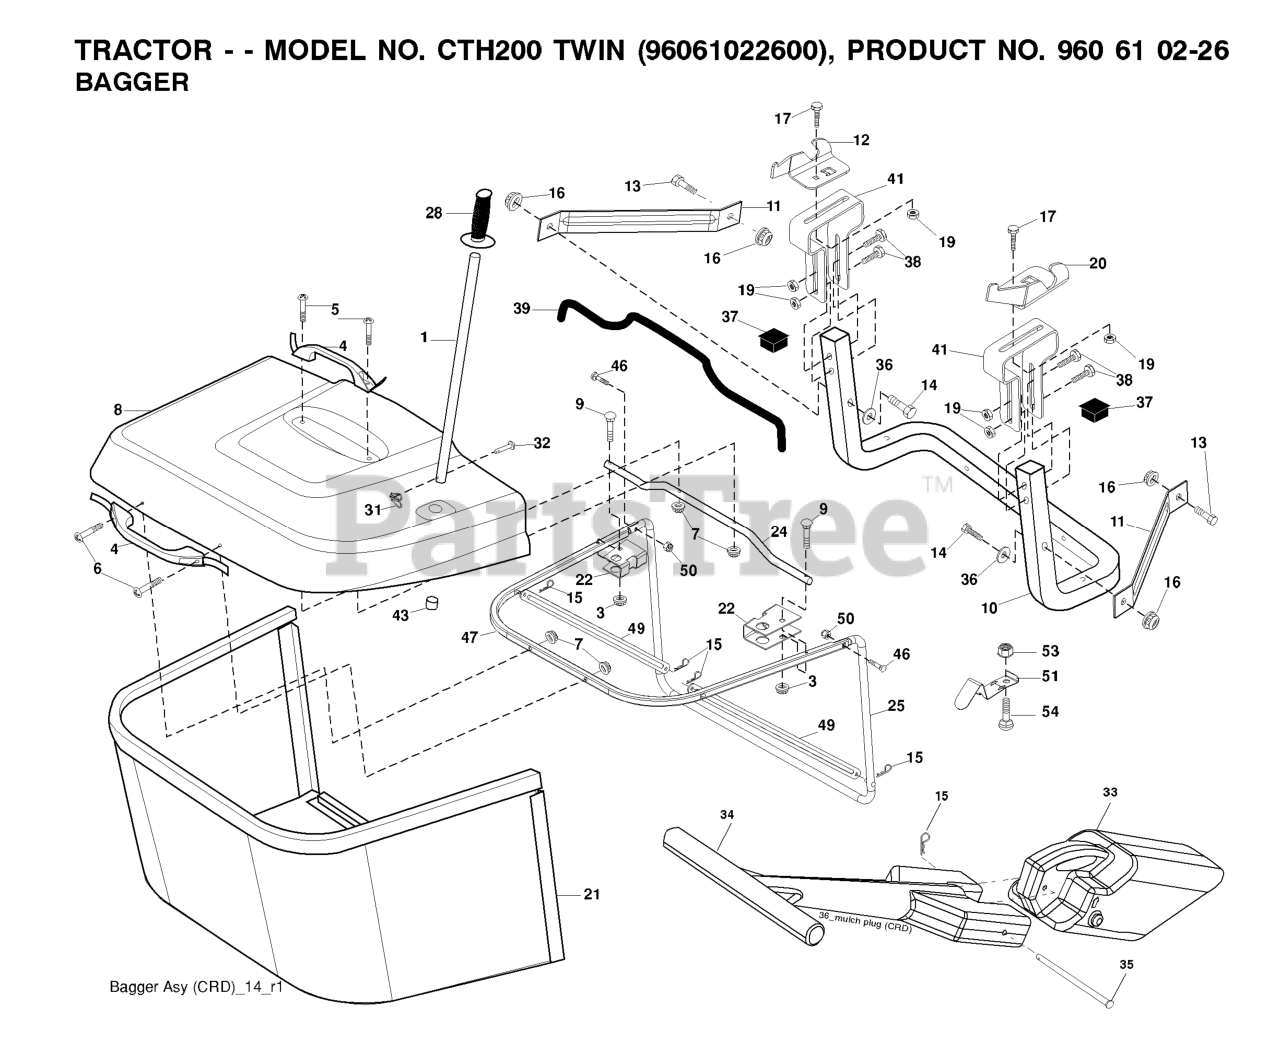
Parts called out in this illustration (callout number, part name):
1	TUBE HANDLE
3	NUT T
4	HANDLE.BAGGER.W/LVRS.BLK.CRD
5	SCREW.PAN.HEAD
6	REPL BY 532 75 00-29
8	COVER.PNT.BGR.CRD.WSLOTS.MS668
9	Bolt Carriage 1/4-20 x 2.25d x Gr.5
10	TUBE
11	BRACKET.SUPPORT.UPPER.BAG.CRD
12	BRKT PIVOT
14	BOLT-HEX EAK
15	RETAINER-SPRNG RB
16	NUT LOCK FLG 3/8-16 UNC
17	RP BOLT 5/16-18 X3/4 ZN/YEL GR
19	NUT LOCK HEX FLANGE 5/16-18
20	BRKT.PIVOT.RH.CRD
21	BAGGER.ASM.CRD.2007
22	BRKT.SIDE.BAG.CRD
24	TUBE.PIVOT.BAG.CRD.BLACK
25	PIPE
28	GRIP.HANDLE.BLACK
31	RETAINER CLIP
32	RIVET,DRILLED
33	MULCH PLUG, CTH150
34	HANDLE.MULCHER.92.CRD (2 2)
36	WASHER
37	Plug Support Bagger CRD
38	BOLT.5/16-18X2.5
39	SEAL.BAGGER.CRD
41	BRKT.VERT.ADJ.BAGGER.CRD
43	PLUG, TUBING END
46	BOLT.CARRIAGE.5/16-18
47	PIPE
49	ROD
50	NUT.71038.31-18.HEX.NYLOCK
51	LATCH
53	NUT
54	BOLT
